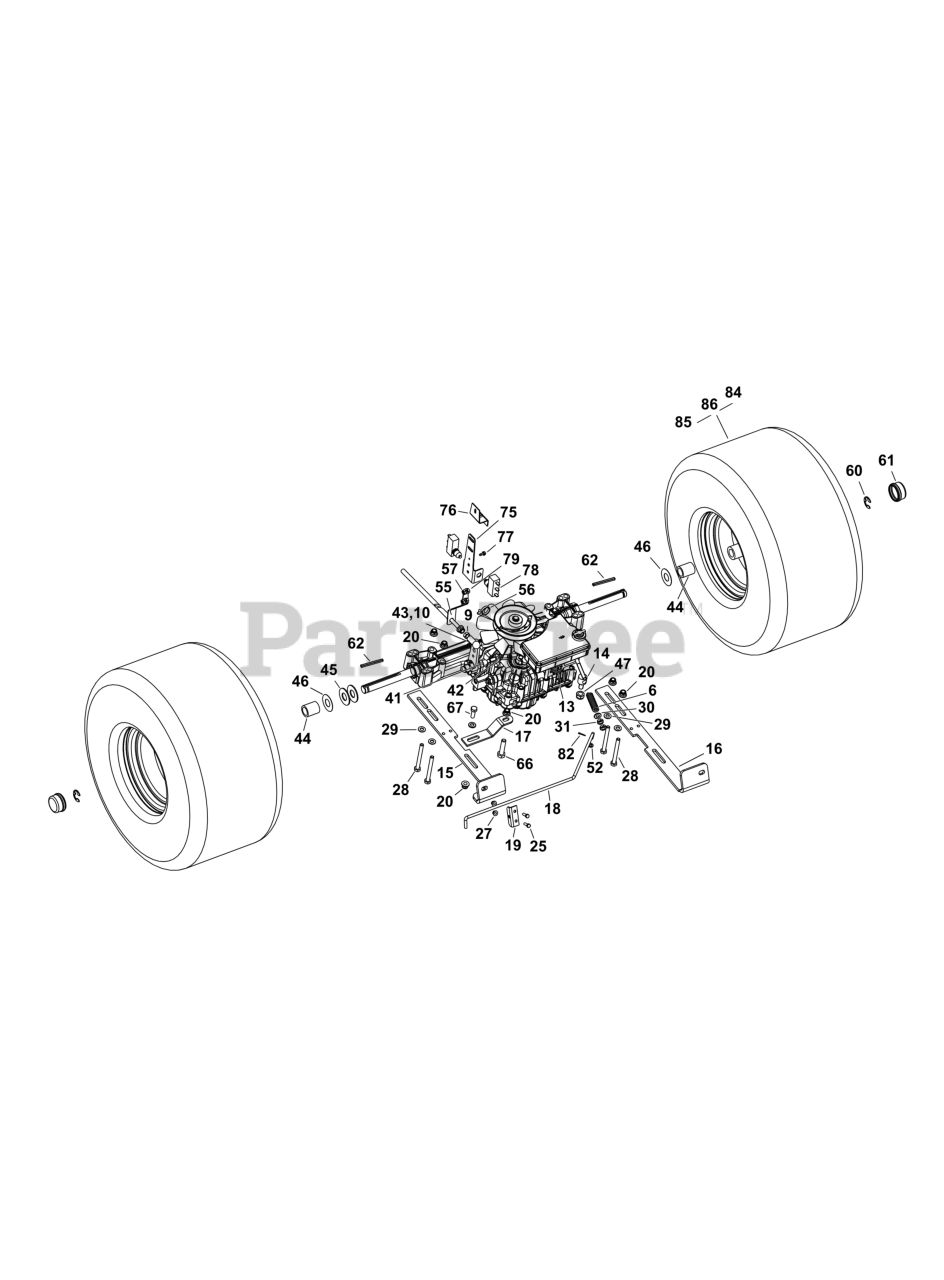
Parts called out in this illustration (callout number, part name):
13	TRANSMISSION
15	PLATE, Left
16	PLATE, Right
18	ROD, Bypass
60	RING, Locking
78	MICROSWITCH
84	WHEEL, Rear
